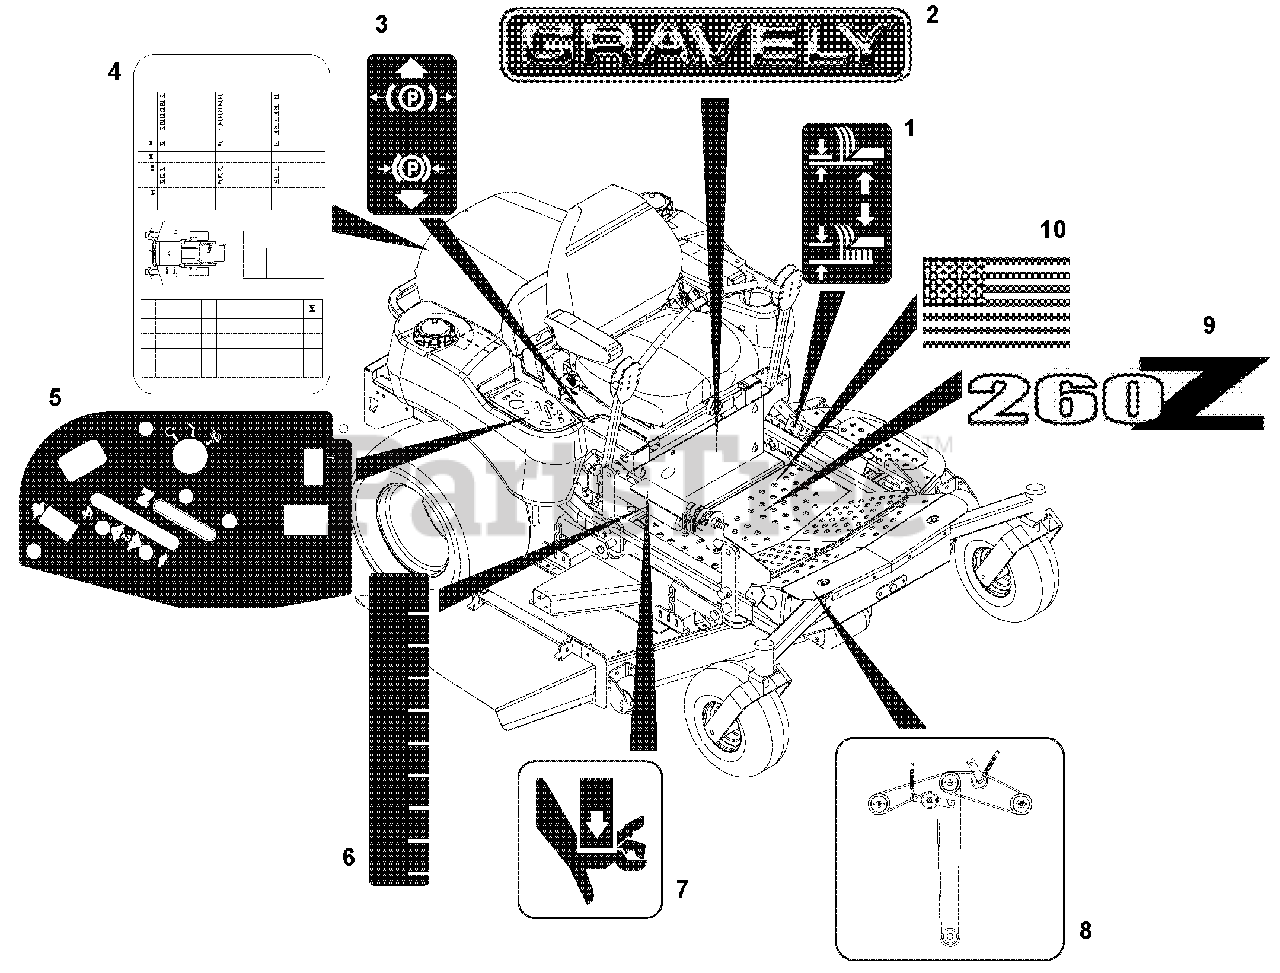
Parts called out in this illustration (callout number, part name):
1	Decal, Lift Lever
2	Decal, 15 Gravely Logo
3	Decal, Parking Brake Lever
4	Decal, Service Instructions
5	Decal, Control Panel (066, 067, 068, 070, 052, 072)
6	Decal, Height of Cut
7	Decal, Pinch Point
8	Decal, Belt Diagram (066, 067, 068, 069, 052, 072)
9	Decal, PM-260Z (067, 068, 069, 072)
10	Decal, American Flag
